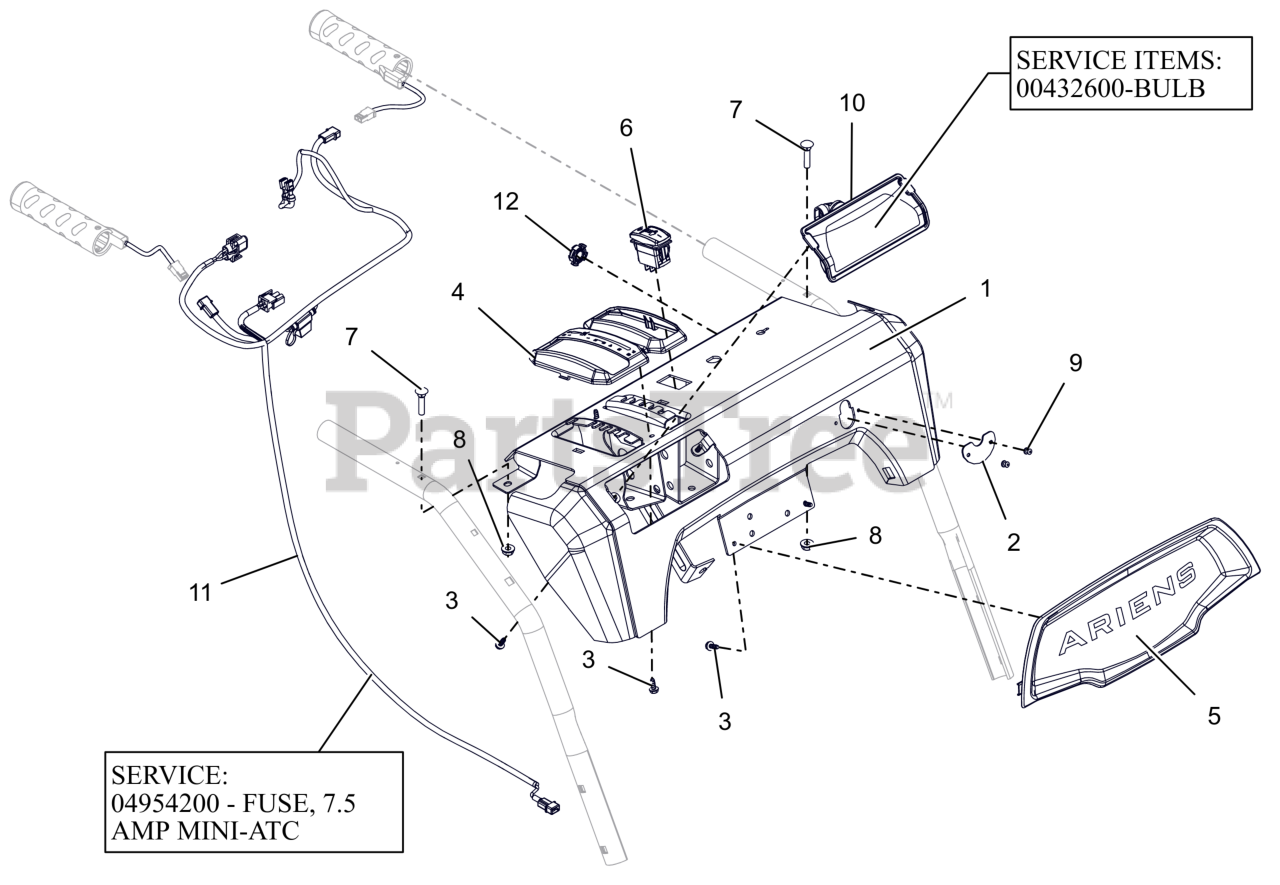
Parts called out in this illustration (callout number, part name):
1	PANEL, CONTROL-EFI ID W/DECAL
2	COVER, DASH BRKT, ID
3	SCR, PLASTIC #10X.50
4	BEZEL, SHIFT - FRICTION SNOW
5	BEZEL, DASH - ARIENS LG DASH
6	SWITCH,ROCKER SPST-ON/OFF
7	BLT-RDHDXLSQNK.25-20X1.25 G5ZC
8	NUT-LK-CTR-FLG .25-20 ZC120
9	RVT-POP #43 .125X.313 STL ZINC
10	HEADLIGHT ASY, HALO 20W 2SHOT
11	HARNESS,LIGHT&WARMER - EFI
12	CRANK BUSHING, NYLON CHUTE BK
